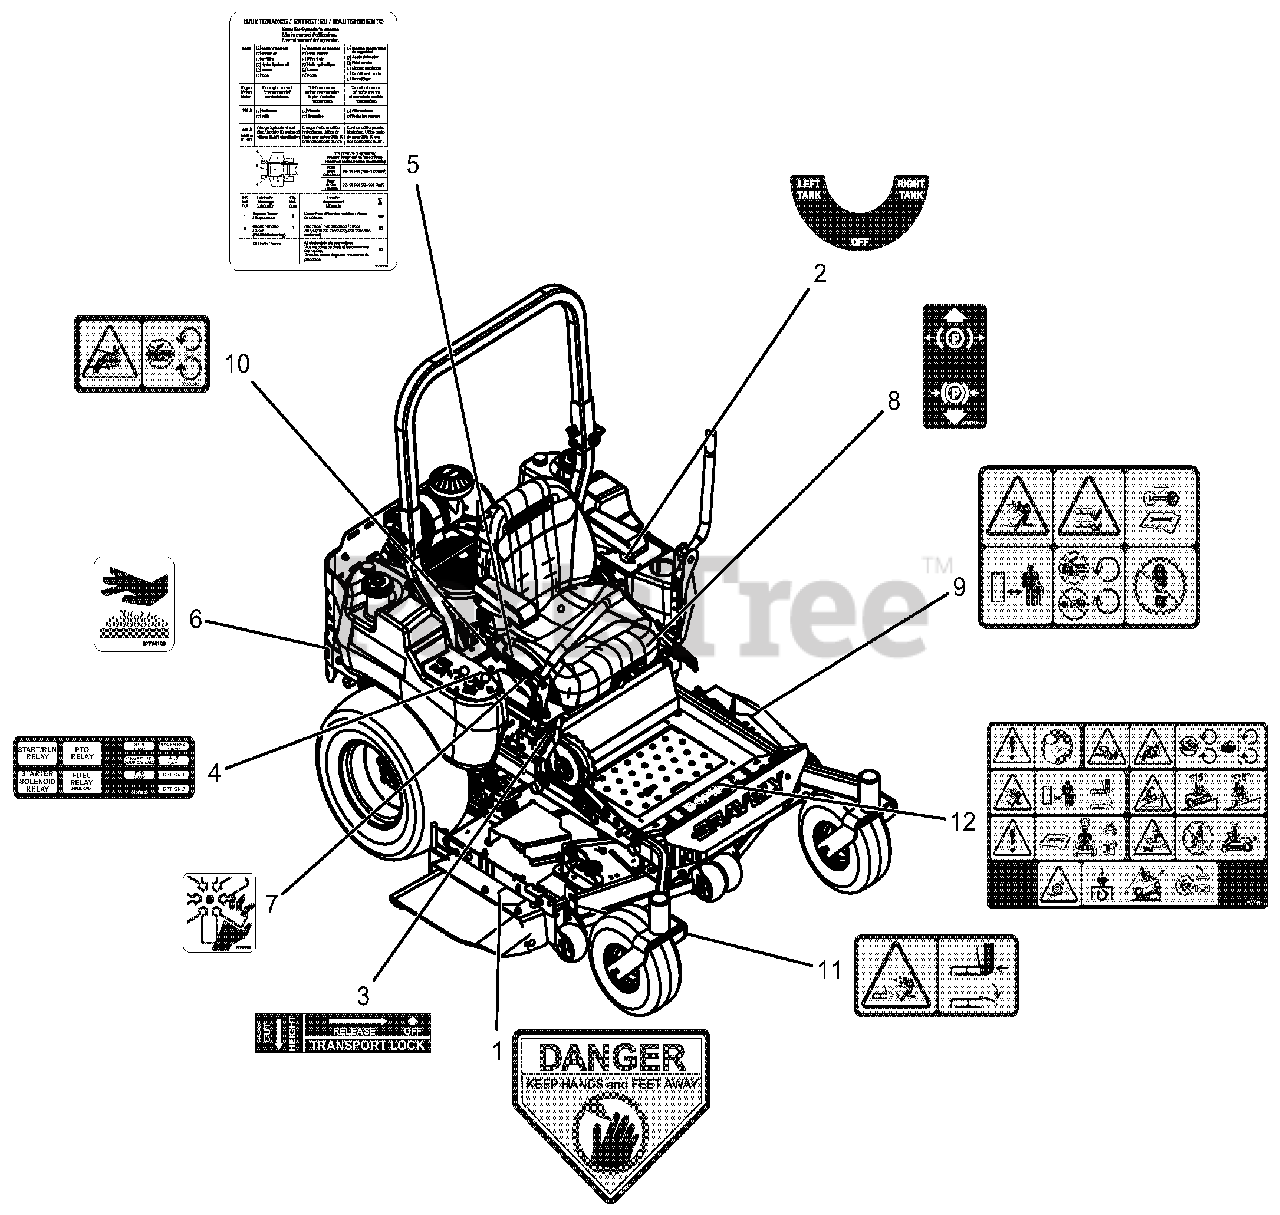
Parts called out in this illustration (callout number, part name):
1	DECAL, DANGER
2	DECAL, FUEL VALVE
3	DECAL, TRANSPORT LOCK INSTRUCT
4	DECAL, FUSE BOX
5	DECAL, MAINT
6	DECAL HOT SURFACE
7	DECAL, DANGER - FAN
8	DECAL, PARKING BREAK LEVER
9	DECAL, SAFETY - MOWER DECK
10	DECAL, SAFETY - GUARDING
11	DECAL, SAFETY - DECK GUARDING
12	DECAL, MAIN SAFETY, COMMERCIAL
